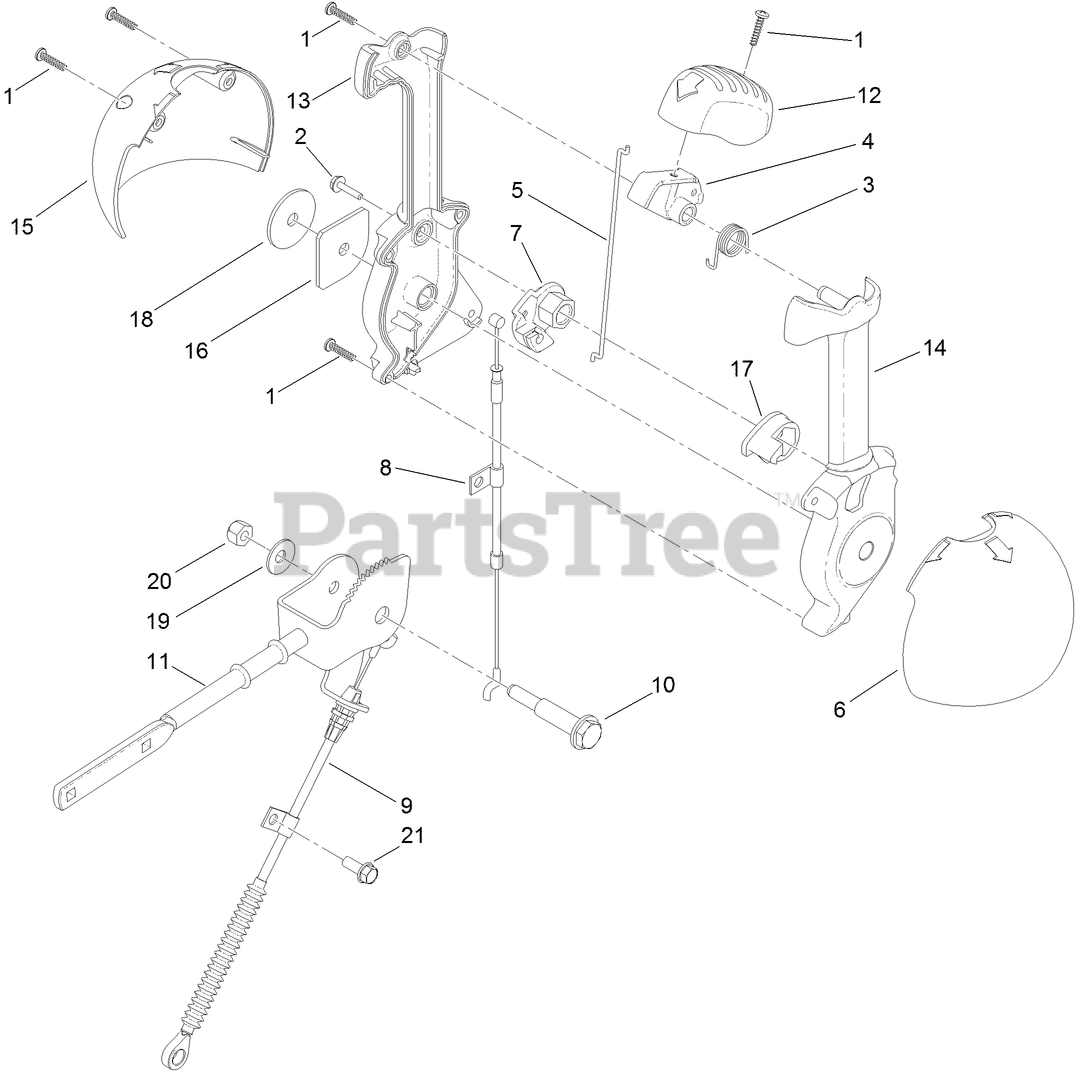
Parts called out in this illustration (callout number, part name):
1	SCREW-PPH
2	SCREW-HWH
3	SPRING-TORSION
4	TRIGGER-LATCH
5	LINK-LATCH
6	COVER-LEVER, CHUTE (LH)
7	LEVER-CABLE, DEFLECTOR
8	CABLE-RELEASE, CHUTE
9	CABLE-DEFLECTOR, CONTROL
10	SCREW-SHOULDER
12	CAP-LEVER
13	LEVER-CONTROL, CHUTE (RH)
14	LEVER-CONTROL, CHUTE (LH)
15	COVER-LEVER, CHUTE (RH)
17	PAWL-LATCH
18	WASHER-NYLON
19	WASHER-BELLEVILLE
20	NUT-LOCK, NI
21	SCREW-HWH
